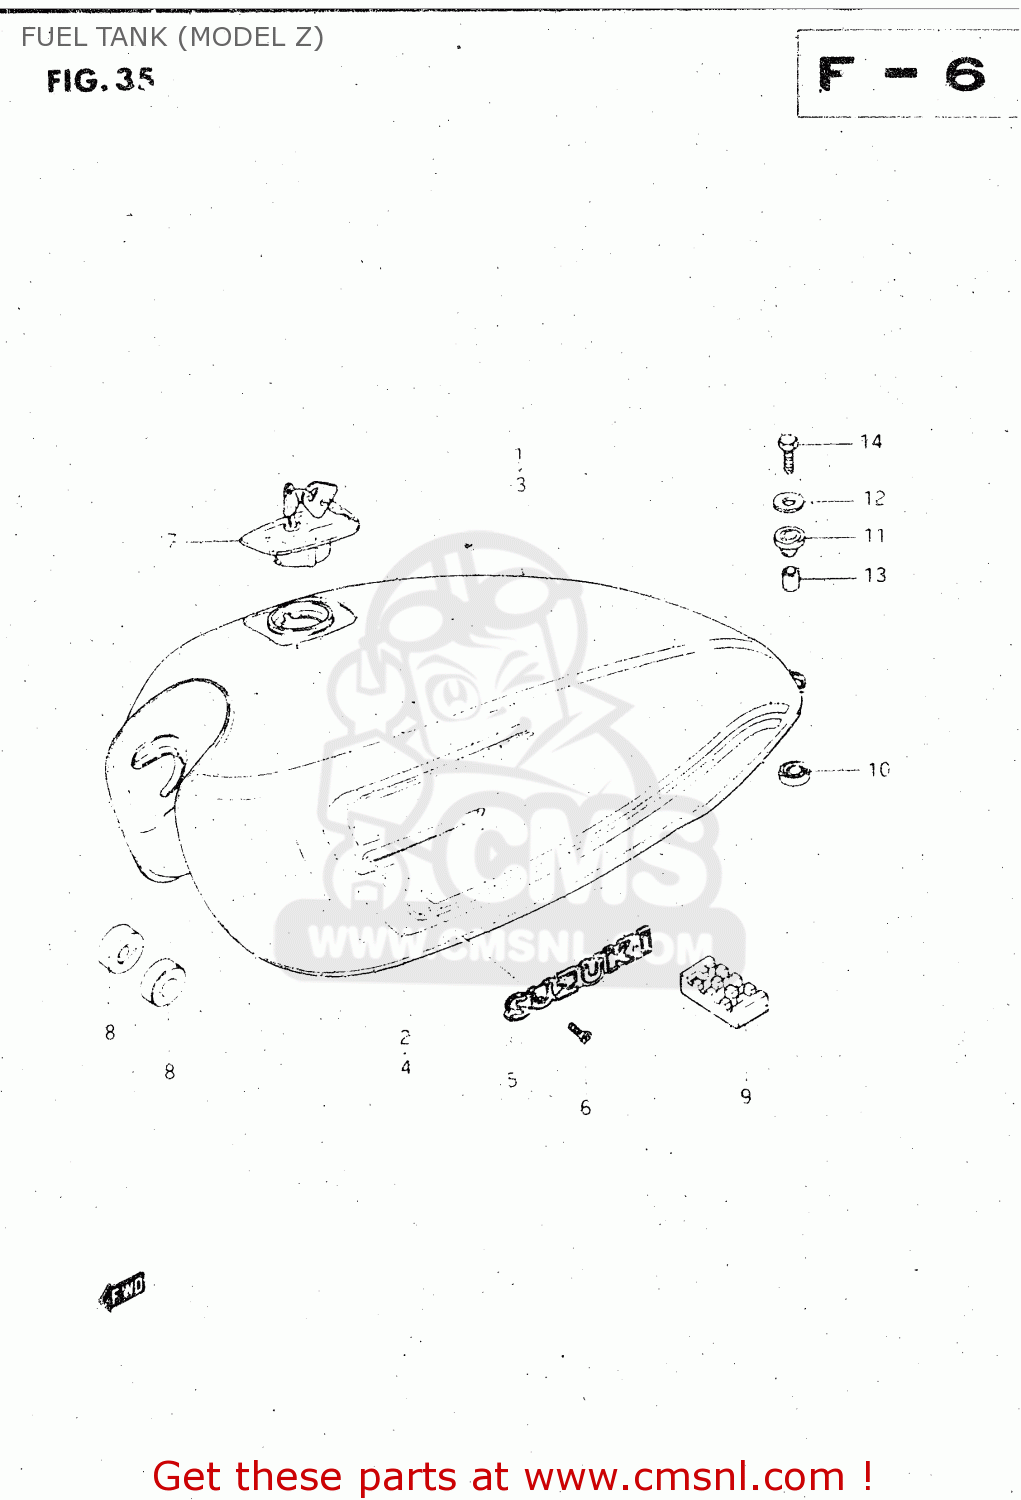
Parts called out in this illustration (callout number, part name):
1	TANK, FUEL (RED)
2	TAPE SET
3	TANK, FUEL (BLUE)
4	TAPE SET
5	EMBLEM,FUEL TANK
6	SCREW 3X6
7	CAP SET,FUEL TANK
8	CUSHION
9	CUSHION,FUEL TANK CTR
10	CUSHION
11	CUSHION
12	WASHER (6.5X24X1.6)
13	SPACER
14	BOLT
